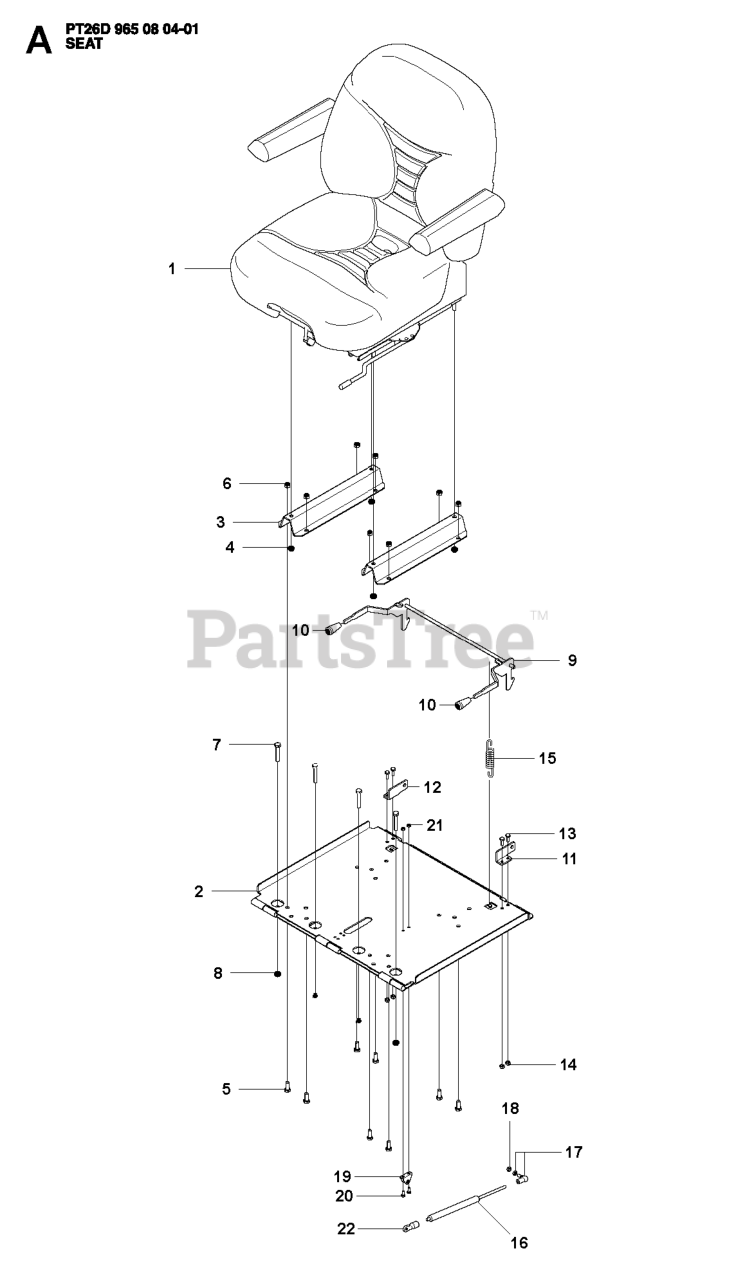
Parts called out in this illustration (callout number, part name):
2	MUFFLER.SINGLE.CYL.KOHL/B&S
9	KEEPER.BELT.ENGINE.3.25 (3 2)
12	PULLEY ENGINE
15	RP TANK FUEL FRT 1.5 GAL
18	FUEL CAP
20	CONTROL.TH/CK.C.
21	SCREW
28	LINE.FUEL.20
29	KIT.SPARK ARRESTOR 794945 B&S
37	HOSE CLAMP
41	LOCKWASHER
43	BOLT HEX 7/16-20X4-1/4"
45	NUT
69	GASKET.EXHAUST.KOHLER
79	SCREW.SOCKET HD.5/16-1
81	TUBE, DRAIN OIL ASM.
82	PLUG DRAIN OIL EASY
83	BOLT.5/16-18UNCX3/4 W/SEMS.BLK
90	SCREW 3/8-16X1
92	SCREW 3/8-16X1
94	RP.TUBE.EXHAUST.KOHL.COURAGE
97	SCREW HEXWSHR 1/4-20X3/4
